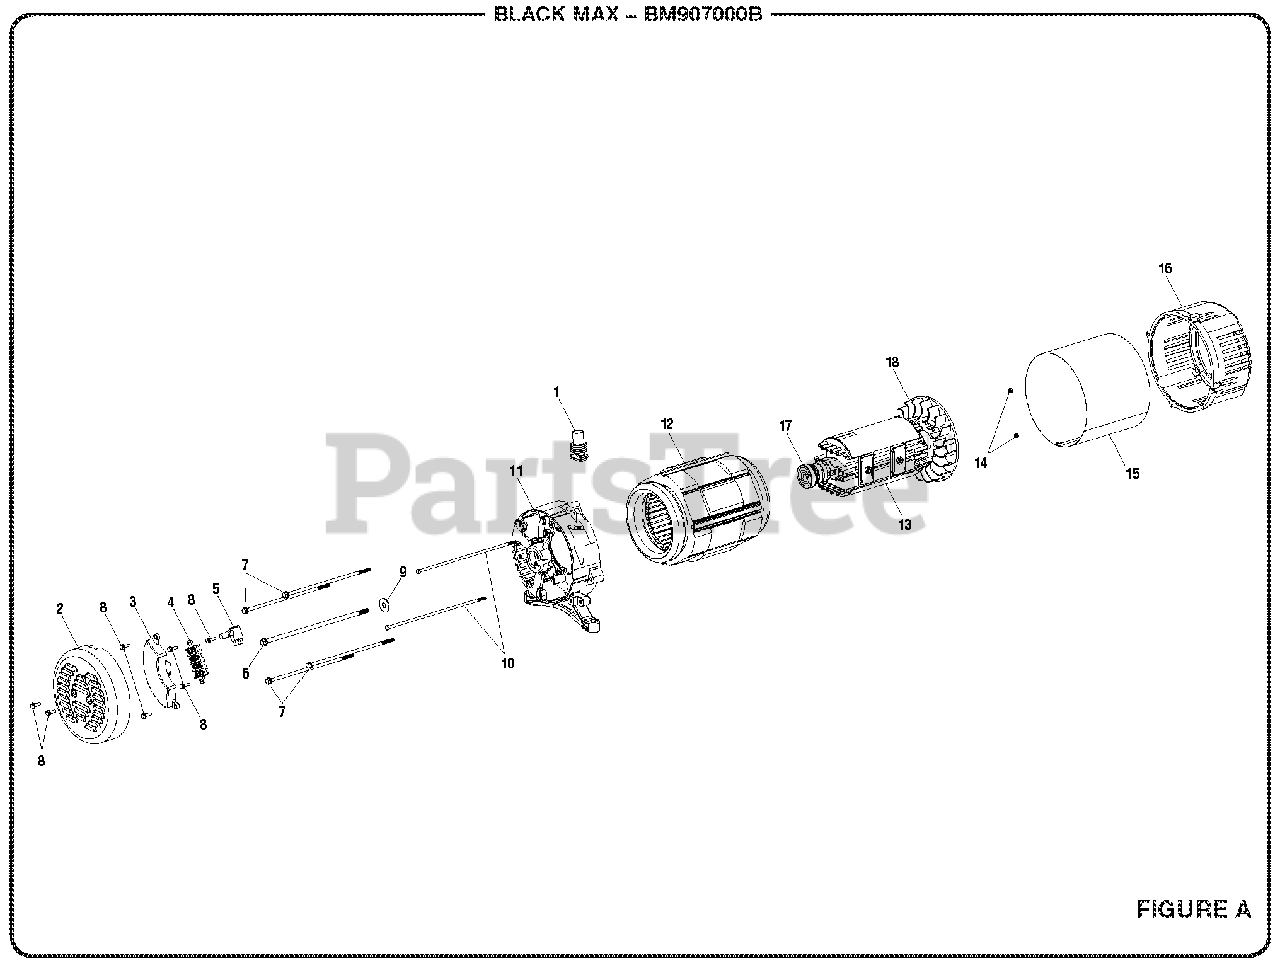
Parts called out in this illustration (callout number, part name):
1	Rubber Boot
2	Brush Cover
3	Automatic Voltage Regulator
4	Terminal Block
5	Brush Assembly
6	Rotor Bolt
7	Stator Bolt
8	Bolt (M5 x 12 mm, Hex Hd.)
9	Rotor Washer
10	Stator Bolt
11	Bearing Housing
12	Stator Assembly
13	Rotor Assembly
14	Hex Nut (M5)
16	Engine Adaptor
